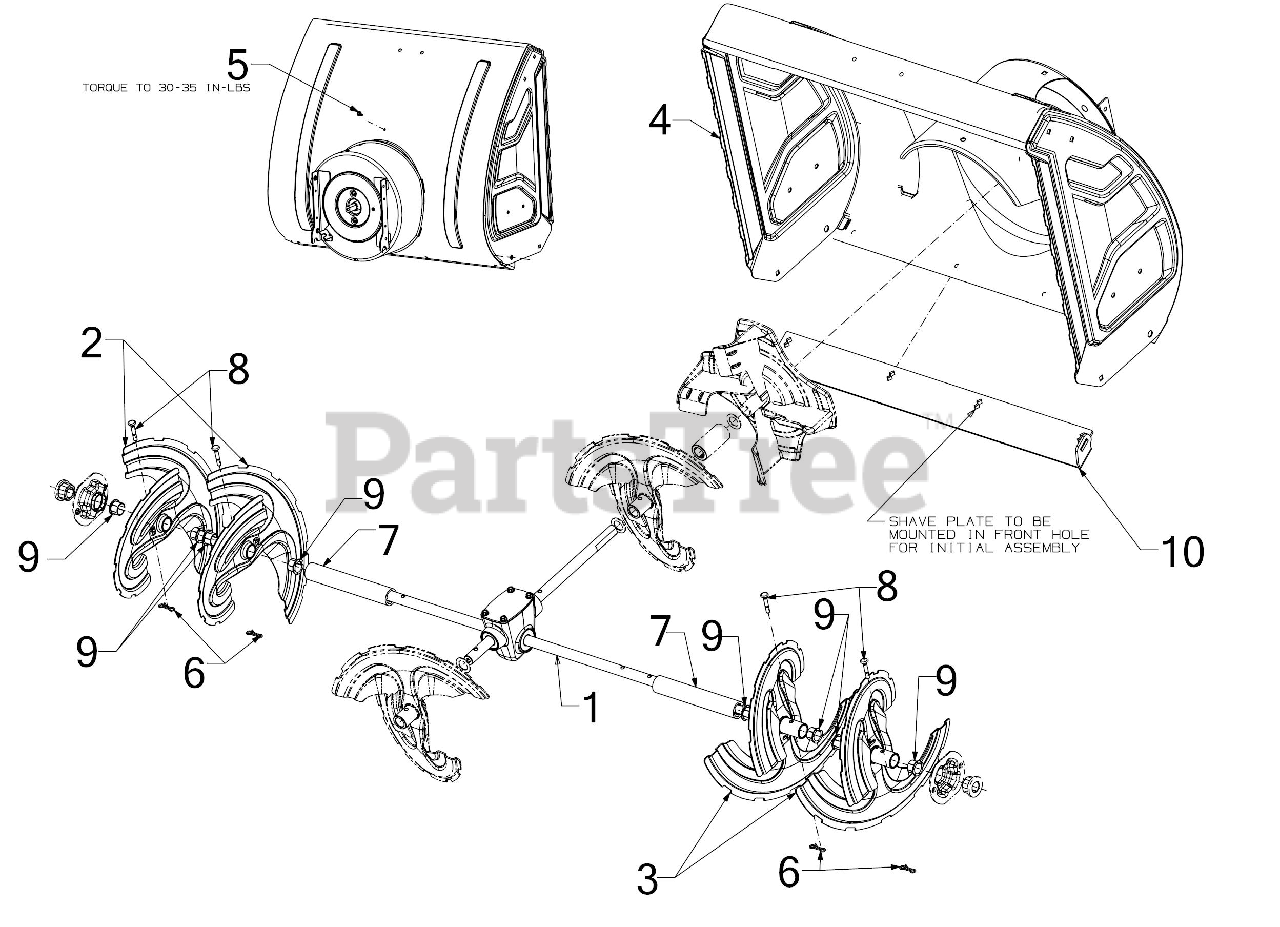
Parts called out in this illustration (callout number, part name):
1	30" AUGER GEARBOX ASSEMBLY
5	SCREW M6-1 x .625
6	BOW TIE COTTER PIN 1/4-5/16
8	SHEAR PIN .25 x 1.50 GR2
9	FLANGE BUSHING
